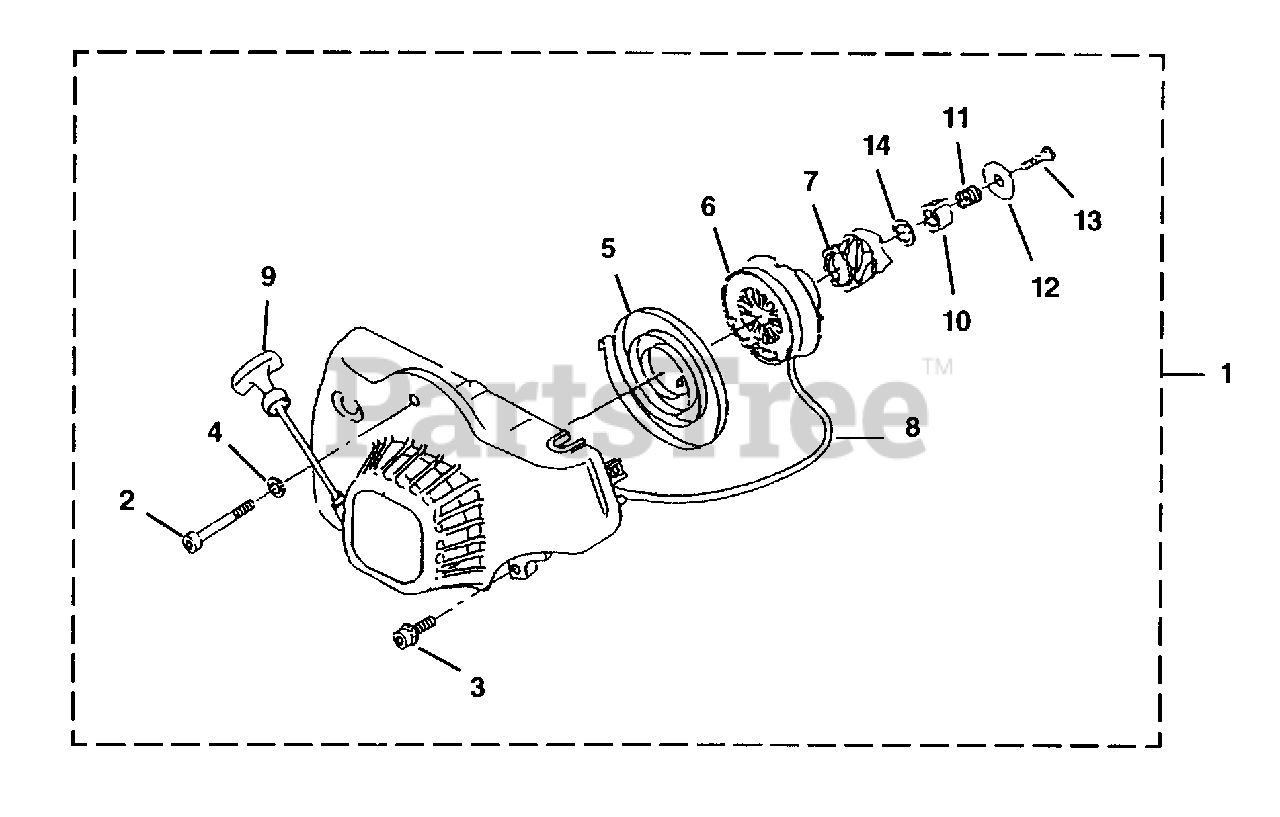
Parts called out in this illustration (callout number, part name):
1	STARTER ASSEMBLY
2	SCREW - Socket Hd (M5 X 50)
3	SCREW-Socket Hd (M5 x 22 W)
8	ROPE-Starter
10	RATCHET GUIDE
11	SPRING - Friction
13	SCREW
14	THRUST WASHER
